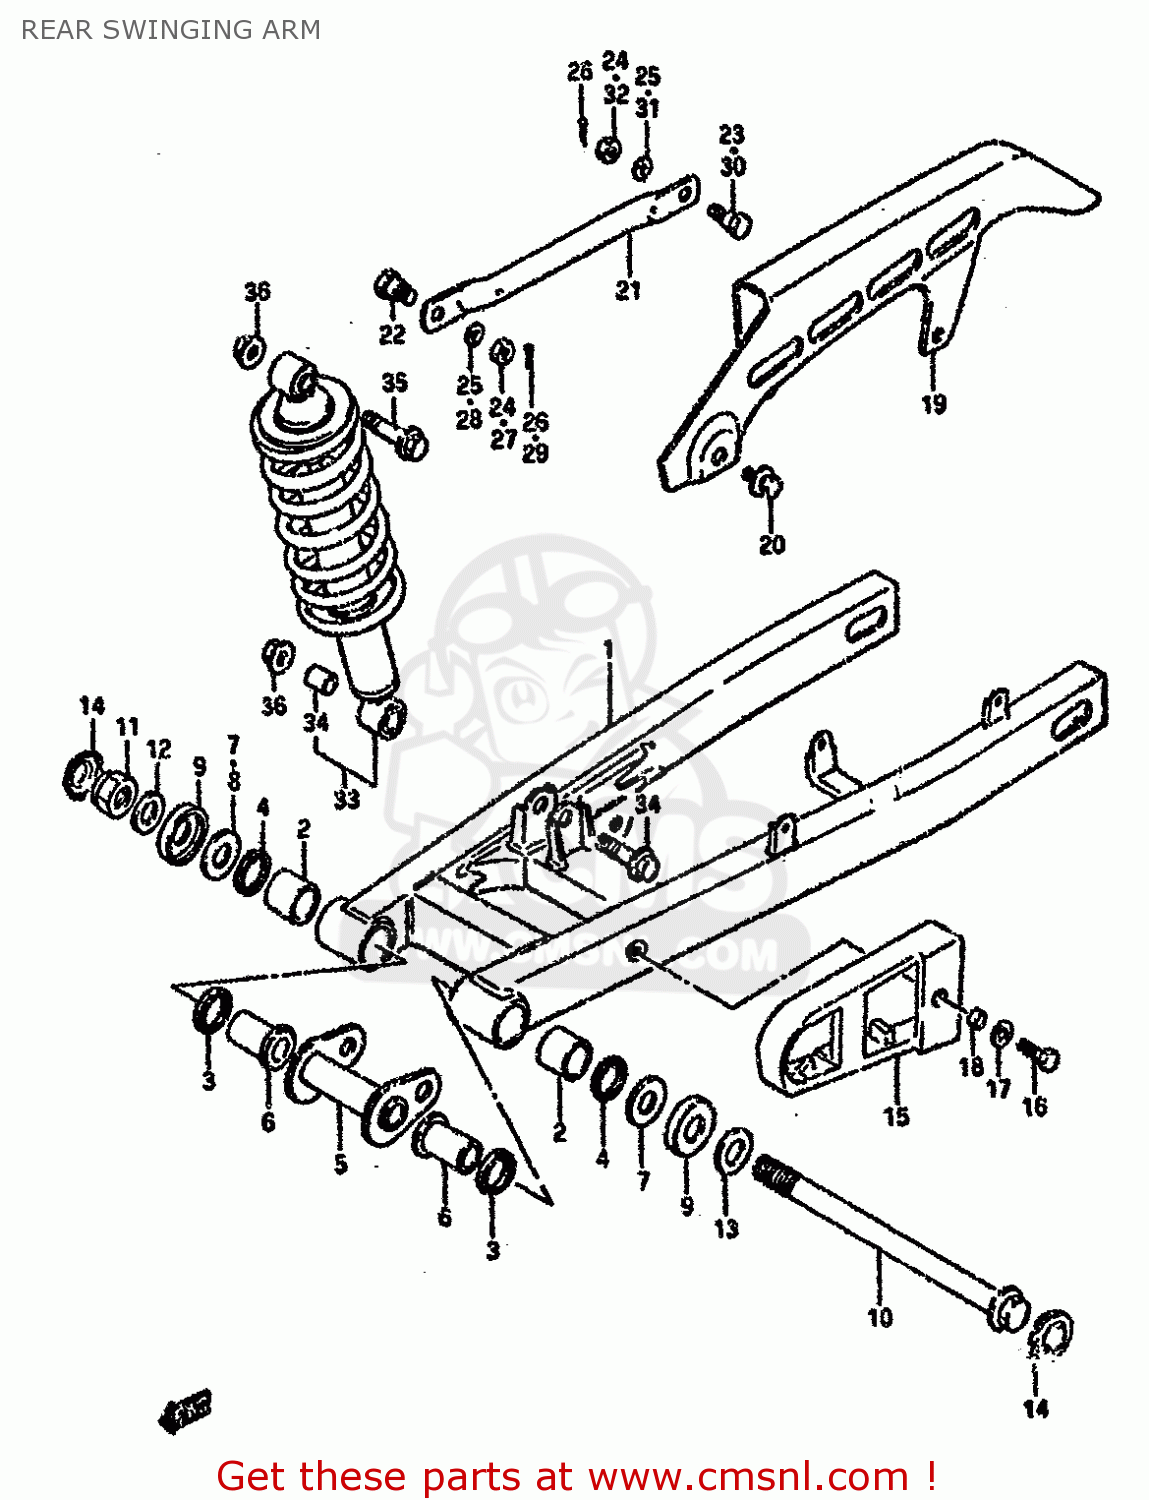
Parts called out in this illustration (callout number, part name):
1	SWINGING ARM ASSY, REAR
2	BUSHING,RR SWGARM PIVOT
3	SEAL,OIL(20X27X5)
4	OIL SEAL
5	SPACER,CENTER
6	SPACER,RR SWGARM PIVOT
7	WASHER
8	WASHER
9	SEAL,RR CUSHION LEVER CTR DUST
10	SHAFT,RR SWINGINGARM PIVOT
11	NUT
12	WASHER(14.2X24X2.3)
13	WASHER
14	CAP,CUSHION LEVER
15	BUFFER, CHAIN TOUCH DIFFENCE
16	BOLT,M6X1X20
17	WASHER(6.5X16X1.2)
18	SPACER
19	CASE,CHAIN
20	BOLT 6X8
21	TORQUELINK,RR
22	BOLT(8X22.5)
23	BOLT(8X26.5)
24	NUT
25	LOCK WASHER
26	PIN 20X20
27	NUT
28	LOCK WASHER
29	PIN 20X20
30	BOLT(8X24)
31	WASHER
32	NUT
33	SHOCK ABSORBER ASSY,REAR
34	COLLAR,ABSORBER ASSY BUSHING
35	BOLT(10X40)
36	NUT
